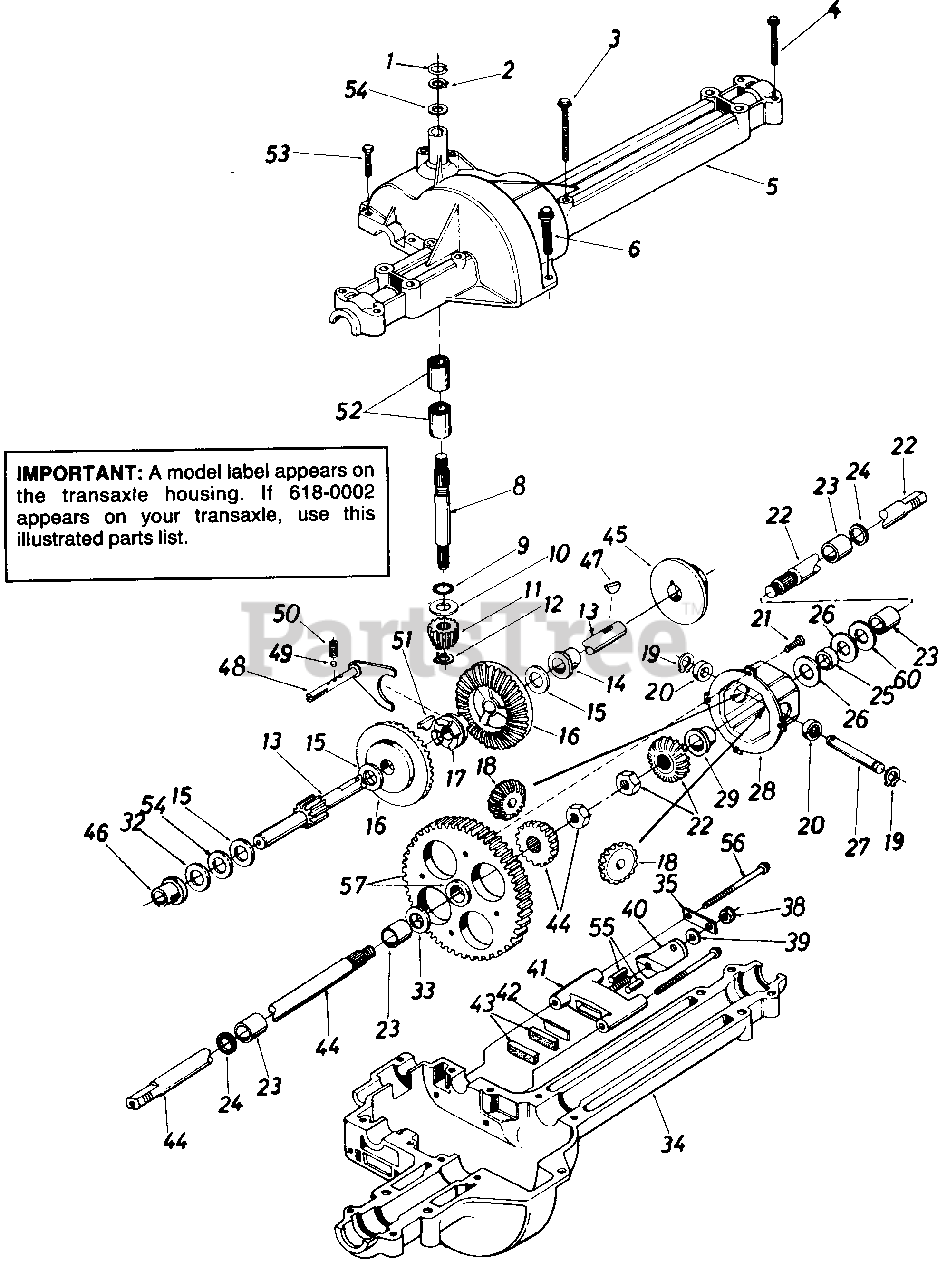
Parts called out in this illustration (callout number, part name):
2	Retaining-Ring
3	Hex Bolt 1/4-20 x 1.75" Lg.
4	Hex Tap Scr. 1/4-20 x 1.25" Lg.
5	Upper Housing
6	Hex TT-Tap Scr. 1/4-20 x .75" Lg.
9	Square Seal 5/8" I.D.
10	Thrust Washer 5/8" I.D. x 1.25" O.D.
11	Pinion Input 14T
12	Retaining Ring
14	Flange Brg. 5/8" I.D. x 3/4" Lg.
15	Fl-Wash. 5/8" I.D. x 1.25"
16	Bevel Gear 42T
17	Clutch Collar
18	Miter Gear 15T (H.D.)
19	Snap Ring
20	Thrust Bearing
21	Pan Head Scr. 1/4-20 x .50" Lg. w/Patch
22	Axle R.H. Ass'y.
23	Sleeve Bearing 3/4" I.D. x 1.0" Lg.
24	Oil Seal 3/4" I.D.
26	Fl-Wash. .760" I.D. x 1.5n O.D.
28	Differential Cam Ass'y.
32	Washer
33	Fl-Wash. .760" I.D. x 1.5n O.D.
34	Lower Housing
35	Anti-Rotation Brkt.
38	Hex Nut 5/16-24 Thd.
39	Fl-Wash. .344" I.D. x .875n O.D.
40	Actuating Arm
41	Brake Yoke
42	Puck Plate
43	Brake Puck
44	Axle L.H. Ass'y.
46	Flange Bearing 5/8" I.D. x 15/16n Lg.
47	Woodruff Key 3/16 x 5/8 HT
48	Shift Fork Ass'y.
49	Ball Detent .250" Dia.
50	Spring Detent
51	#9 Hi-Pro Key 3/16" x 3/4" Dia. HT
52	Needle Brg. 5/8" l.D. x 1/2" Lg.
53	Hex Bolt 1/4-20 x 1.00" Lg
54	Fl-Wash. 5/8" l.D. x 1" O.D. x .020 Thk.
55	Actuating Pin 5/16" Dia.
56	Hex Wash Hd. Self-Tap Scr. 1/4-20 Thd.
57	Differential Gear 72T Ass'y. w/Bearing
60	Washer
